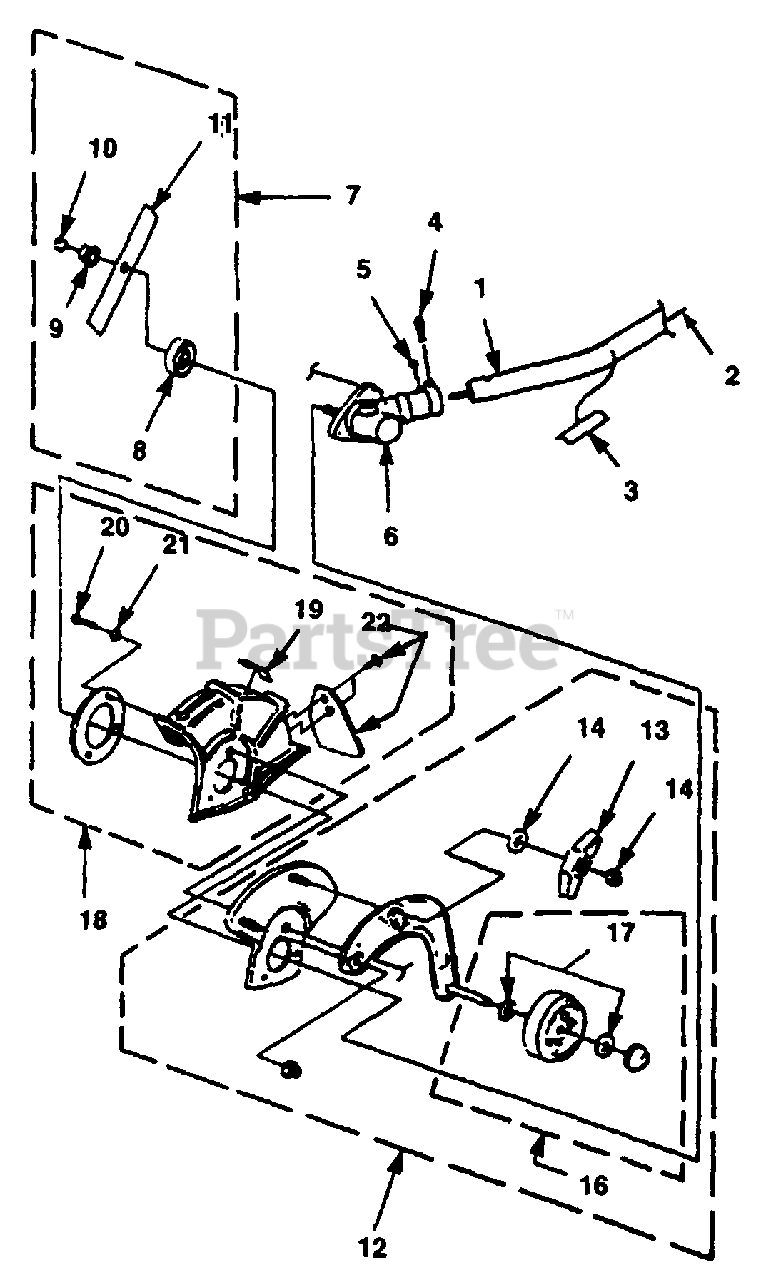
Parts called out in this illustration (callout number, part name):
1	DRIVE SHAFT HOUSING
2	SHAFT - Flexible
3	DECAL - Warning
4	SCREW - Cap Socket Hd. (1/4-20 X 7/8")
5	SCREW - Sems Hex Hd. (10-24 X 1/2")
6	GEAR HEAD
7	BLADE KIT
8	WASHER - Flanged
9	WASHER - Flanged
10	NUT - Lock
11	BLADE, 2" X 9"
12	SUPPORT ARM ASSEMBLY
13	KNOB - Adjusting
14	NUT - Hex
16	WHEEL KIT
17	WASHER - Flat
18	GUARD KIT
19	DECAL - Warning
20	SCREW - Hex Hd. (10-24 X 5/8")
21	WASHER - Lock
22	FLAP KIT
